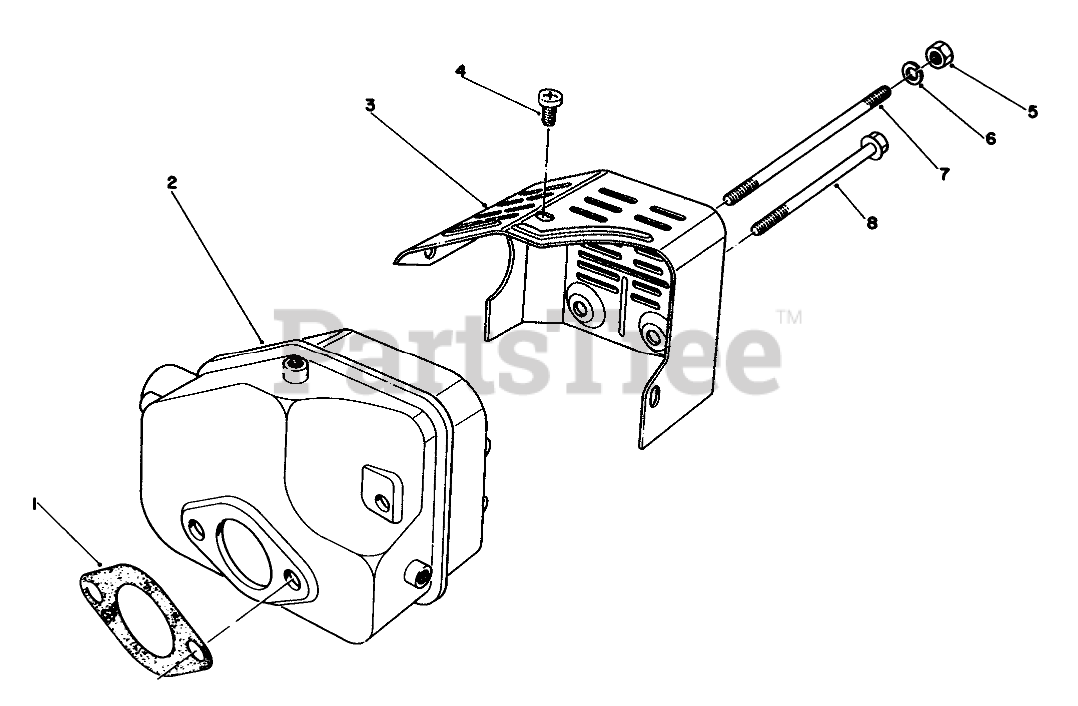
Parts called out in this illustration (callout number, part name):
1	GASKET
2	Muffler
3	COVER
4	SCREW
6	WASHER-LOCK
